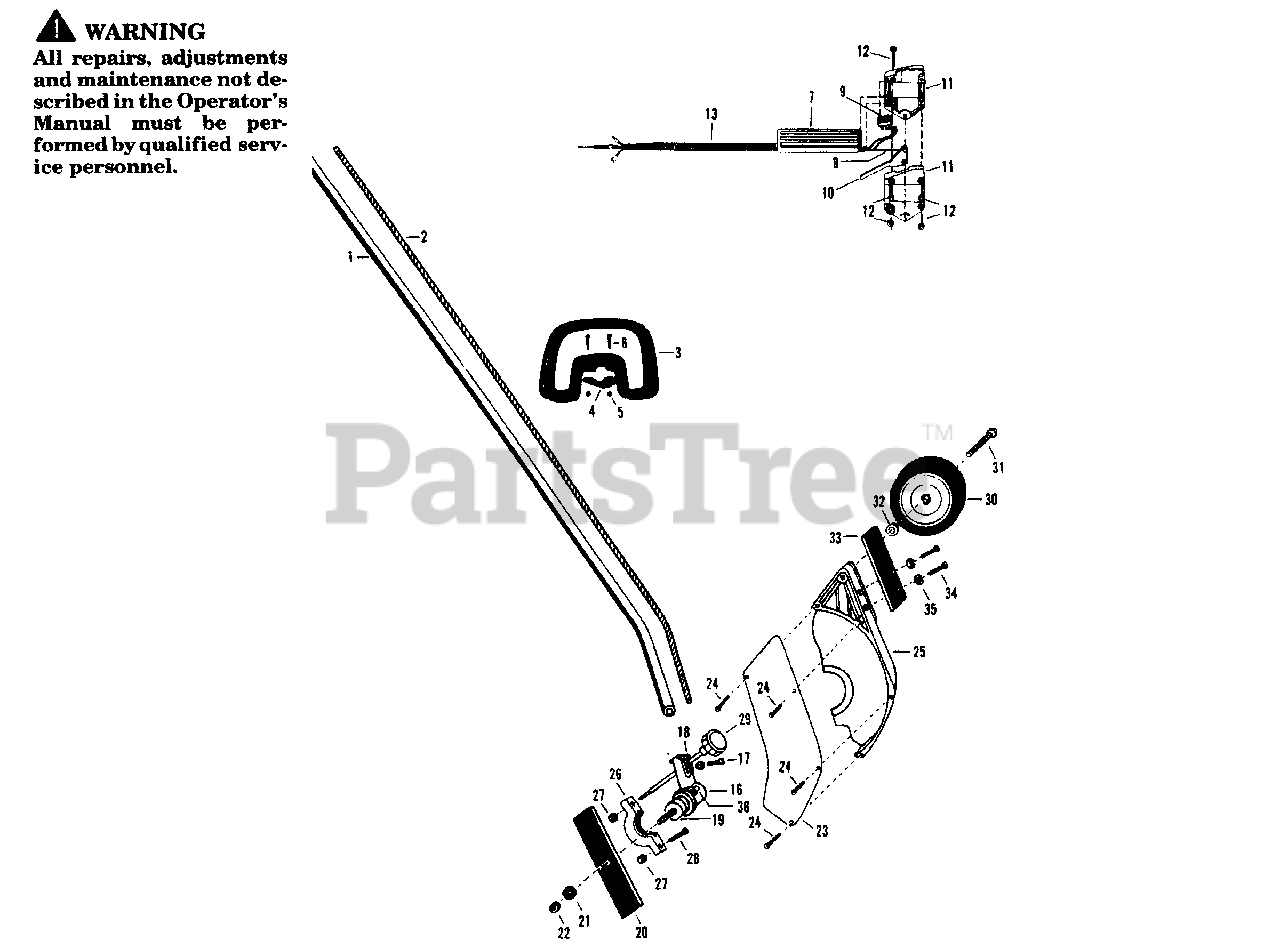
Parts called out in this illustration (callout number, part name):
1	Drive Shaft Housing
2	Flexible Drive Shaft
3	Tear Drop Handle (Incl. 4-6)
4	Clamp, Handle
6	Screw, Button Hd. Cap
8	Throttle Cable
9	On/Off Switch w/Wires
10	Trigger
11	R.H. & L.H. Housing
12	Screw Kit, Throttle Housing
13	Cable & Wire Cover
16	Gear Head Ass'y (Inc. 18 - 19) (Outside vendor part number)
18	Screw/Washer Kit (Inc. 17 & 18)
19	Cup Washer
21	Blade Washer
23	Side Plate
25	Blade Guard
26	Blade Guard Bottom
29	Adjustment Knob
33	Debris Flap
36	Grease Plug
